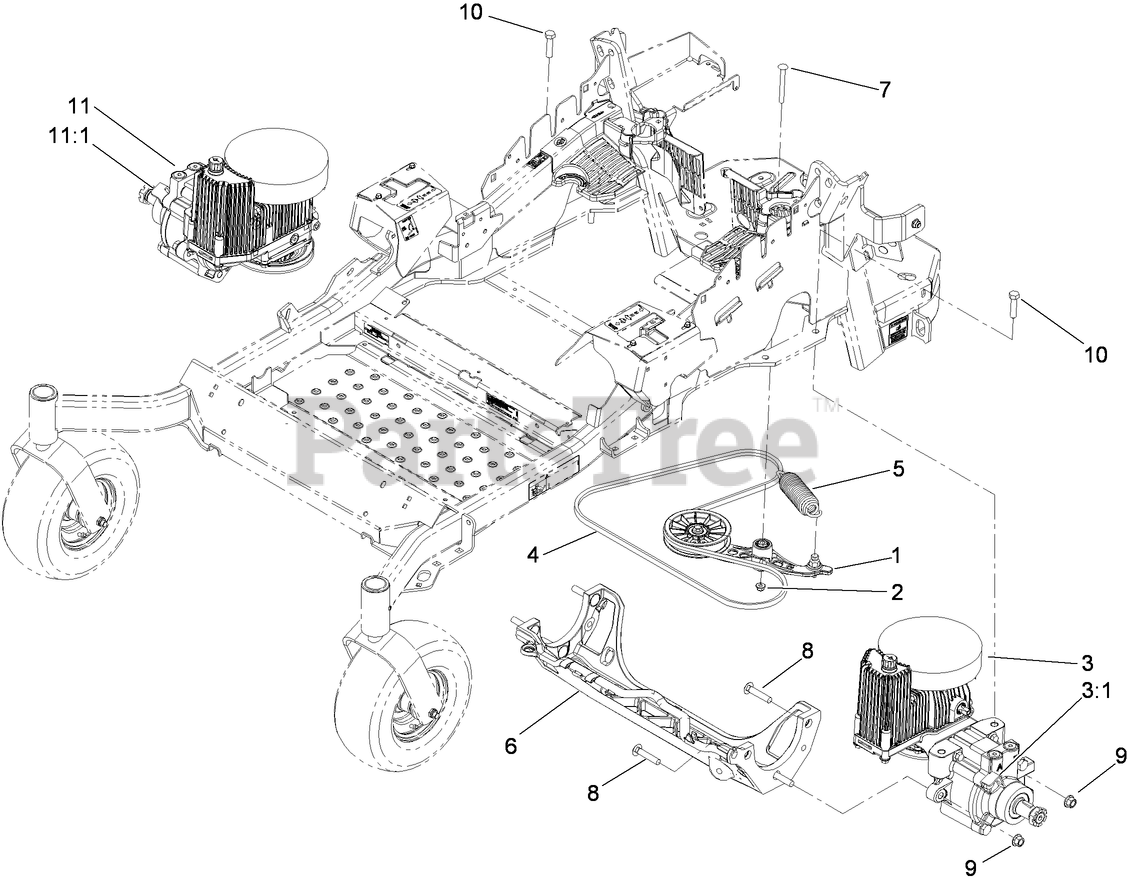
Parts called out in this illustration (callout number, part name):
1	PUMP IDLER ASM
2	NUT-HF, NI
3	HYDRO-LH, 12CC (W/CHECK)
3:1	BRACKET-ANCHOR, CABLE
4	BELT-V
5	EXTENSION-SPRING
6	CRADLE-HYDRO
7	BOLT-CARRIAGE
8	SCREW-CARR
9	NUT-LOCK
10	SCREW-HH
11	HYDRO-RH, 12CC (W/CHECK)
11:1	BRACKET-ANCHOR, CABLE
